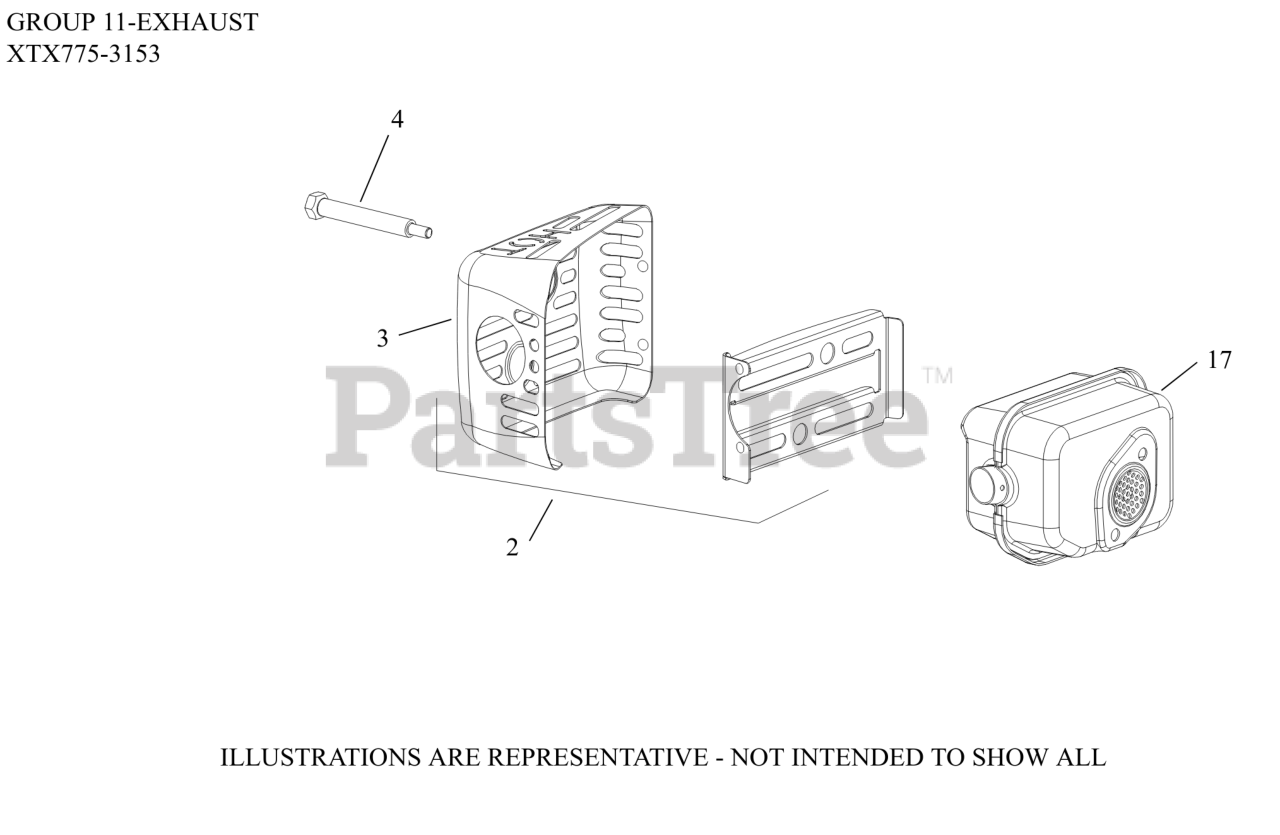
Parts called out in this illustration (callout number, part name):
2	GUARD, MUFFLER ASSEMBLY
3	GUARD, MUFFLER - DISCONTINUED
4	SCREW, SHOULDER
17	MUFFLER, ASSEMBLY
